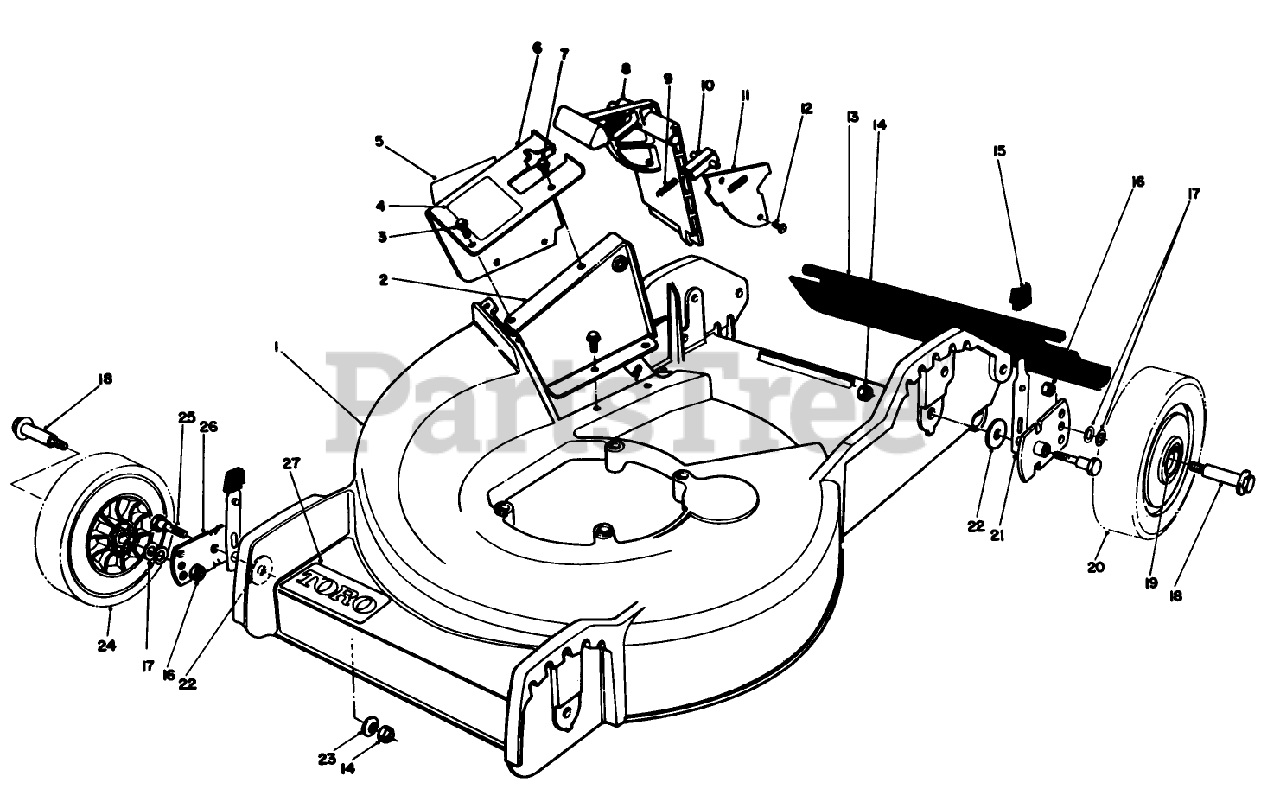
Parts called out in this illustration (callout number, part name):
1	HSG & CARTON
3	SCREW
5	DECAL-DANGER
7	SCREW
9	SPRING-COMPRESSION, LATCH
11	DOOR COVER
13	SHIELD - TRAILING
14	NUT-LOCK, NI
15	KNOB-ARM
17	WASHER
18	BOLT-WHEEL
19	BUSHING
20	WHEEL TIRE ASM 8 IN
21	SPRING ARM ASM
22	PIVOT WASHER
23	WASHER-BELLEVILLE
25	5/16-18 PIVOT SCREW
26	Pivot Arm Assembly
27	DECAL
